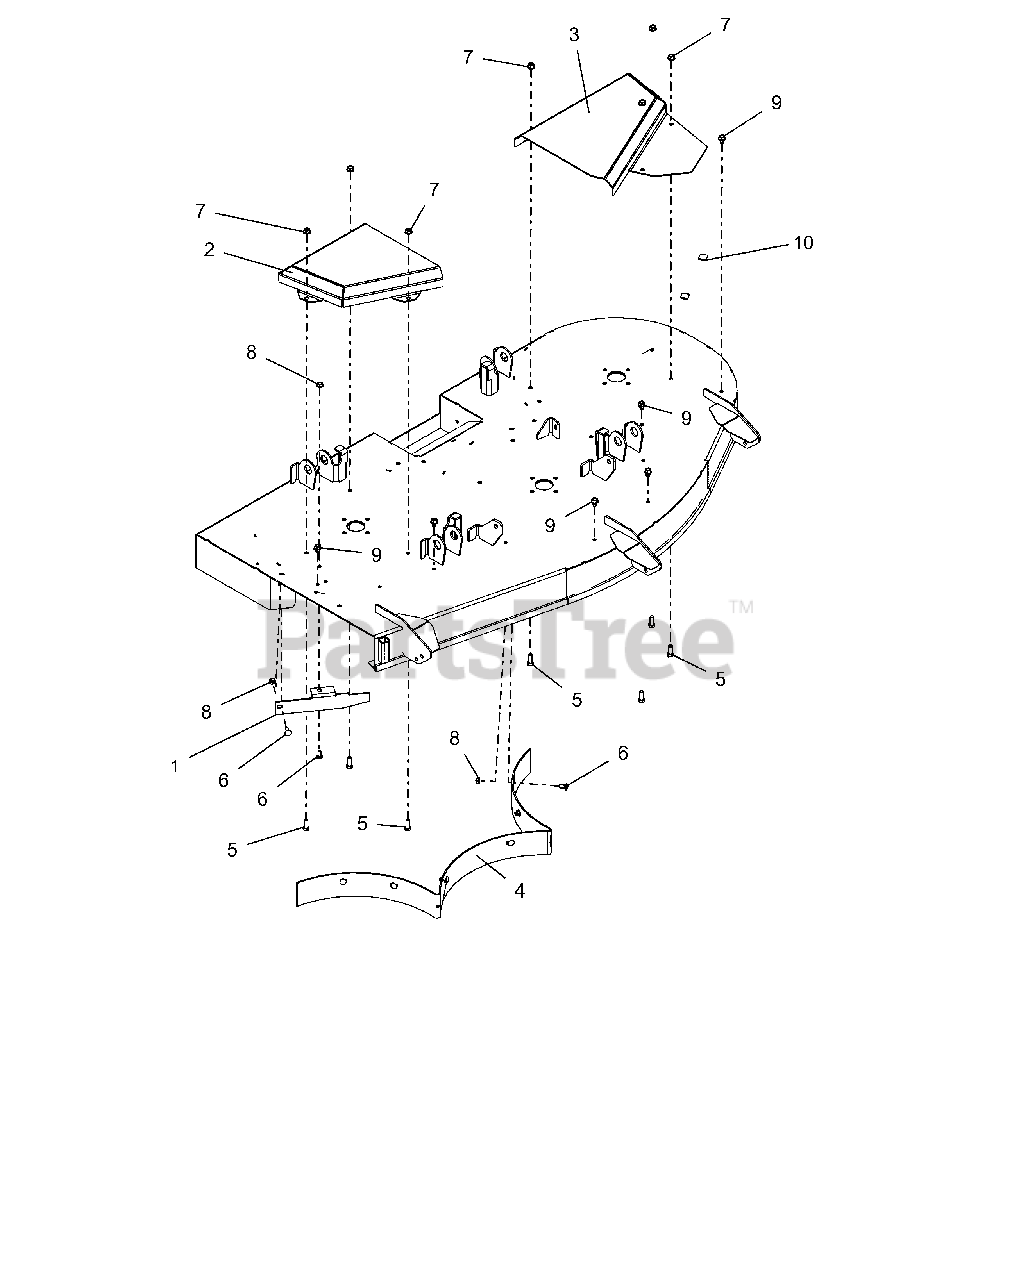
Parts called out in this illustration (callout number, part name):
1	BAFFLE, DISCHARGE 60"
2	COVER, BELT RH 60"
3	COVER, LH BELT 60
4	BAFFLE, REAR BOLT-IN, 60" XL
5	@BLT-HEX .38-16X1.00 GR5 YWZC
6	@BLT-RDHDSQNK .31-18X.75 G5YZ
7	@NUT-LK-TOP-FLG .38-16 YWZC
8	@NUT-LK-TOP-FLG .31-18 YWZC
9	@SCR-TAP .38-16X.50 HWH TR YWZ
